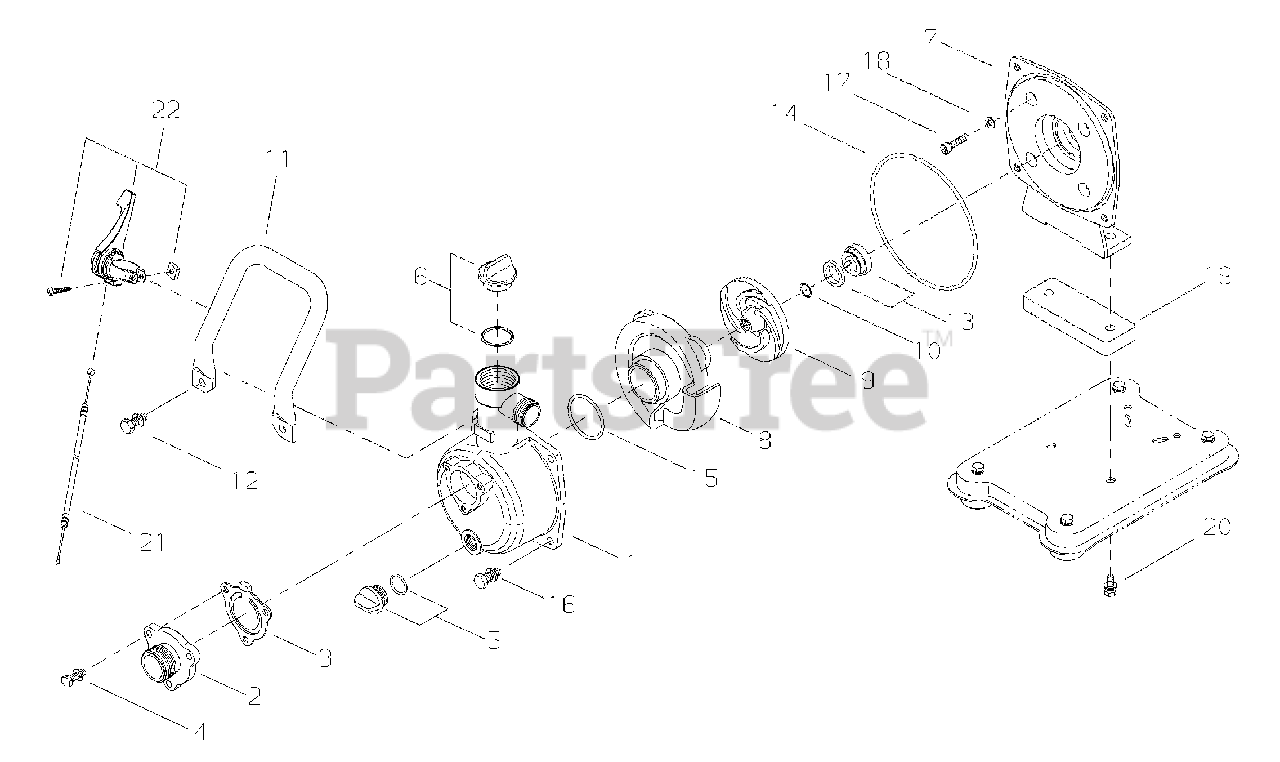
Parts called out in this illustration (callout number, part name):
1	CASE, PUMP
2	SUCTION CONNECTION
3	PORT GASKET
4	BOLT - 6X20
5	DRAIN PLUG ASSY
6	FILLER PLUG ASSY
7	COVER, PUMP
8	CASE, IMPELLER
9	IMPELLER
10	SHIM
11	HANDLE
12	BOLT - 8X22
13	SEAL
14	O-RING
15	O-RING
16	BOLT - 8X20
17	BOLT - 6X55
19	SPACER - 9
20	BOLT - 8X25
21	CABLE, THROTTLE
22	THROTTLE LEVER ASSY
